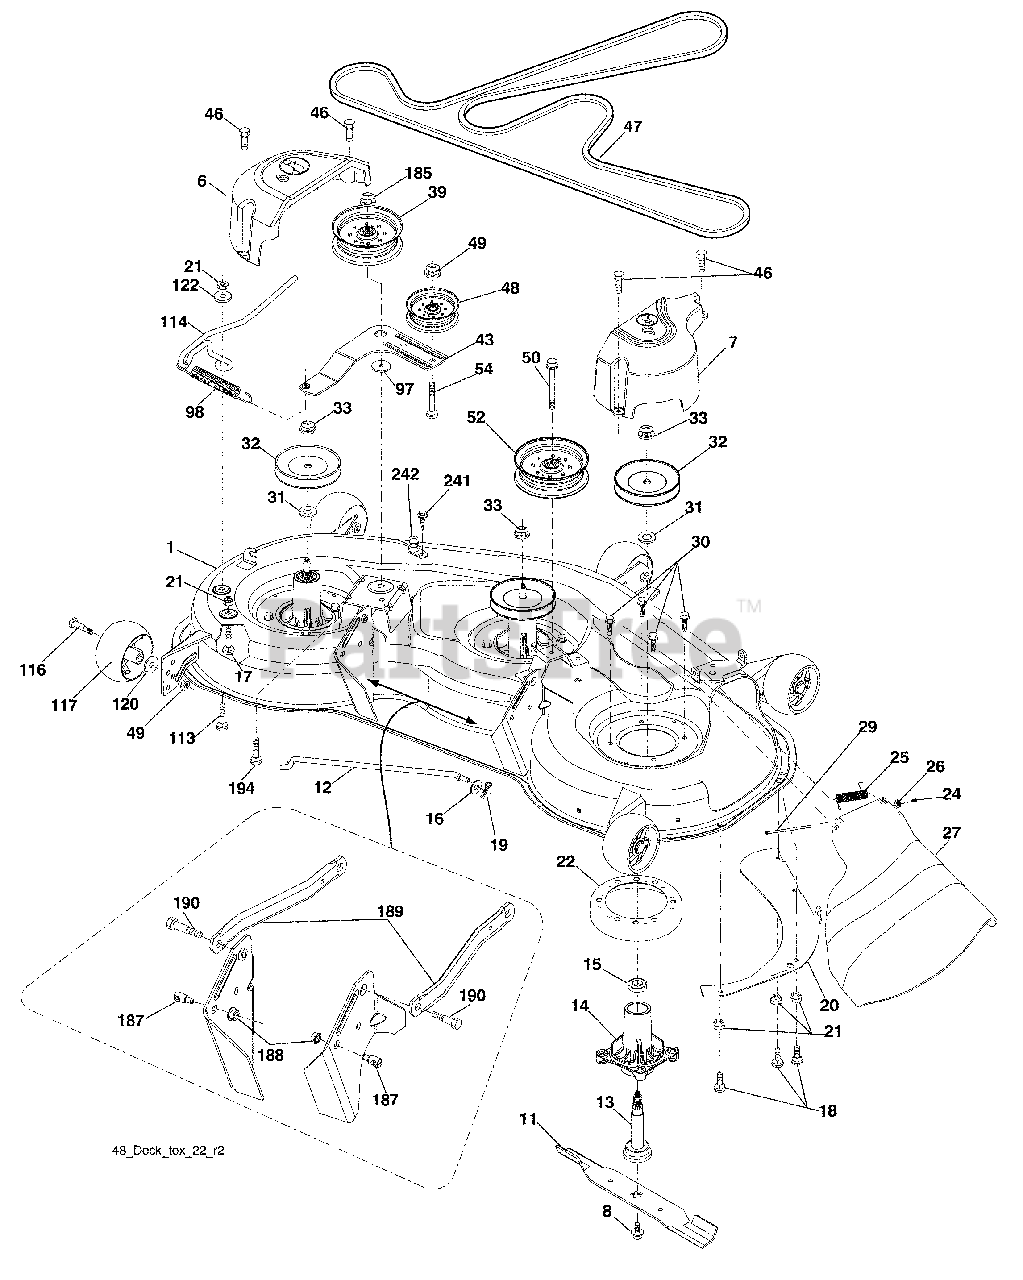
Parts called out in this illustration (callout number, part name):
1	Deck Weldment Mower
6	Cover Mandrel LH
7	Cover Mandrel RH
8	Bolt/Washer Asm 7/16-20 unf
11	Blade High Lift
12	Rod Anti Sway
13	Shaft Asm. w/Lower Bearing
14	Housing, Mandrel
15	Bearing, Ball, Mandrel
16	Washer 13/32 x 13/16 x 12 Ga.
17	Bolt Carr 5/16-18 x 5/8
18	Bolt RdHd 5/16-18 unc x 5/8
19	Pin Cotter 5/16 Bow Tie Lock
20	Baffle, Vortex
21	Nut, Crownlock 5/16-18 unc
22	Stripper
24	Cap Sleeve
25	Spring, Torsion
27	Deflector Shield
29	Rod, Hinge
30	Screw, Thdroll Washer Head
31	Washer, Spacer Mower Vented
32	Pulley, Mandrel
33	Nut, Flg. Top Lock
39	Pulley, Idler, 4.50 HUB
43	Arm, Idler
46	Screw, Thdroll. 1/4-20 x 5/8
47	Belt Deck Drive
48	Pulley, Idler Primary
49	Nut, Lock Flg. 3/8-16 unc
50	Screw 3/8-16 x 2-1/4
52	Pulley Idler 4.50 RAW
54	Bolt Carr. 3/8-16 x 1-1/2 Gr. 5
97	Washer Hardened
98	Spring Drive
113	Bolt Rdhd Sqnk 5/16-18 x 3/4
114	Rod Tension Relief
116	Bolt, Shoulder
117	Gauge Wheel
120	Washer 13/32 x 1-1/4 x 12 Ga.
122	Bushing Tension Relief
185	Nut Lock Flange 7/16-14 Gr. 5
187	Stud Fastener w/"D" Anti-Rotation
188	Nut Lock Hex Flange
189	Arm Susp. Mower Rear
190	Bolt Shoulder
194	Bolt Carr Sqnk 7/16-24 x 2
241	Screw TT #10-32.5. 3/8 Flange
242	Port Washout
